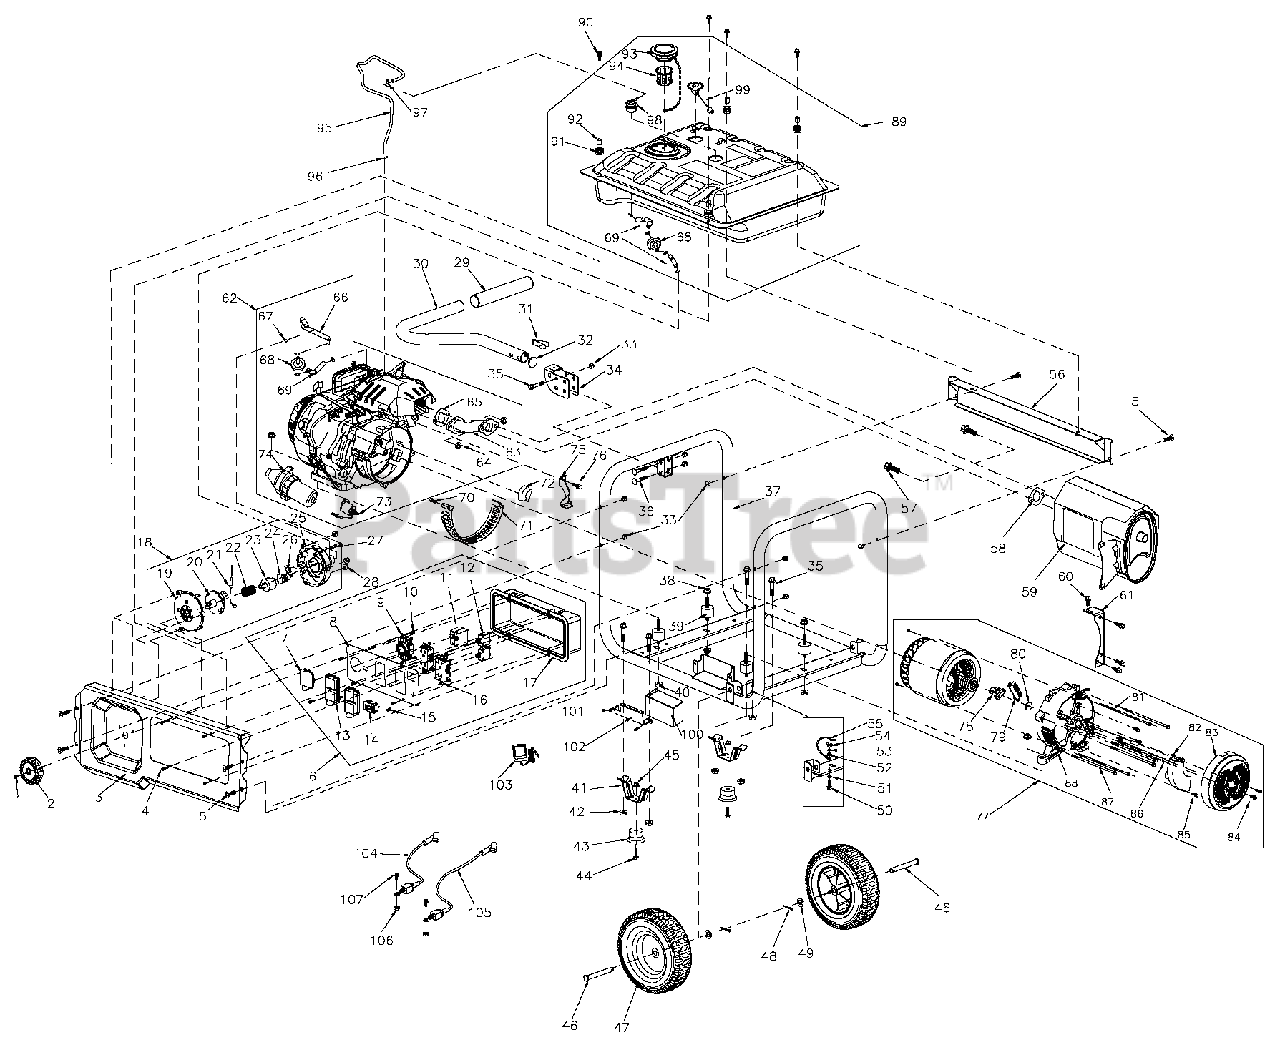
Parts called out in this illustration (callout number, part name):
1	SCREW, PLATE M5X10
2	KNOB, POWER DIAL
3	RAIL, FRAME, CP SIDE
4	SCREW, SELF TAPPING, ST4.0X16
5	BOLT, CURVED HEAD, M8X40
6	PANEL ASSY., CONTROL
7	COVER, OUTLET
8	FACE PLATE, CONTROL PANEL
9	OUTLET, 30A 120/250V SPCGR
11	BREAKER, CIRCUIT, 30A
12	BREAKER, CIRCUIT, 20A
13	COVER, OUTLET
14	METER, HOUR
15	CHARGER, INPUT
16	OUTLET, 20A, 120V DUPLEX 6342
17	COVER, BACK PANEL
18	SWITCH, POWER DIAL COMBINATION
19	COVER, POWER DIAL
20	SHAFT, POWER DIAL
21	CHOKE, LASSO
22	SPRING, COMPRESSION
23	ADAPTER, POWER DIAL
24	SWITCH, POWER DIAL FUEL
25	CASE, POWER DIAL
26	SWITCH, MICRO
27	SWITCH, MICRO
29	HANDLE, GRIP
30	HANDLE, BLACK
31	BUTTON, SNAP
32	PLUG, HANDLE
33	CAP, NUT LOCKING, M8
34	BRACKET, HANDLE, BLACK
35	BOLT, M8X45
36	BOLT, CARRIAGE HEAD M8X46
37	FRAME, BLACK
38	NUT, M10
39	MOUNTS, VIBRATION RUBBER
41	FRAME, BENT FOOT
42	NUT, M8
43	FOOT, RUBBER
44	BOLT, M6X28
45	NUT, M6
46	PIN, AXLE
48	PIN, COTTER
49	WASHER, FLAT, 13X2
50	BOLT, M6X20
51	WASHER, LOCK SPECIAL
53	WASHER, FLAT 6X0.8
54	NUT, M6
55	WIRE ASSY., GROUND
56	RAIL, BACK
57	BOLT, M8X25
58	GASKET, MUFFLER EXHAUST
59	MUFFLER
60	BOLT, M8X16
61	BRACKET, MUFFLER
62	ENGINE, 420 CC
63	PIPE, EXHAUST MANIFOLD
65	GASKET, EXHAUST CYLINDER
66	HOSE, FUEL 12.7X250
67	CLAMP, HOSE #12
68	FILTER, FUEL (IN-LINE)
69	HOSE, FUEL, 12.7X75
70	BOLT, M5X10
71	COVER, DUST
73	RELAY, STARTER
74	MOTOR, STARTER
75	BRACKET, AIR CLEANER
76	BOLT, M6X12
77	ALTERNATOR ASSY.
78	BRUSH, ALTERNATOR
79	TERMINAL, WIRE CONNECTOR
80	WASHER, FLAT M10X4
81	BOLT,STATOR M5X220
83	COVER, GENERATOR END
84	BOLT, M5X12
85	BOLT, M5X16
86	BOLT, ROTOR, M10X275
87	BOLT, ROTOR, M6X185
88	HOUSING, RR BEARING CARRIER
89	TANK ASSY., FUEL 8 GAL.
90	BOLT, M8X20
91	MOUNT, RUBBER FUEL TANK
92	INSERT, MOUNT ANTI-CRUSH
93	CAP, FUEL TANK
94	FILTER, FUEL (TANK)
95	HOSE, PREFORMED FUEL
96	CLAMP, HOSE #12
97	CLAMP, FUEL HOSE #10
98	VALVE, ROLL-OVER
99	GAUGE, FUEL
100	BATTERY
101	BOLT, M6X12
102	COVER, BATTERY COMPARTMENT
103	CHARGER, BATTERY
104	CABLE, BATTERY (POS-RED)
105	CABLE, BATTERY (NEG-GRN)
106	NUT, M5
107	BOLT, M5X12
